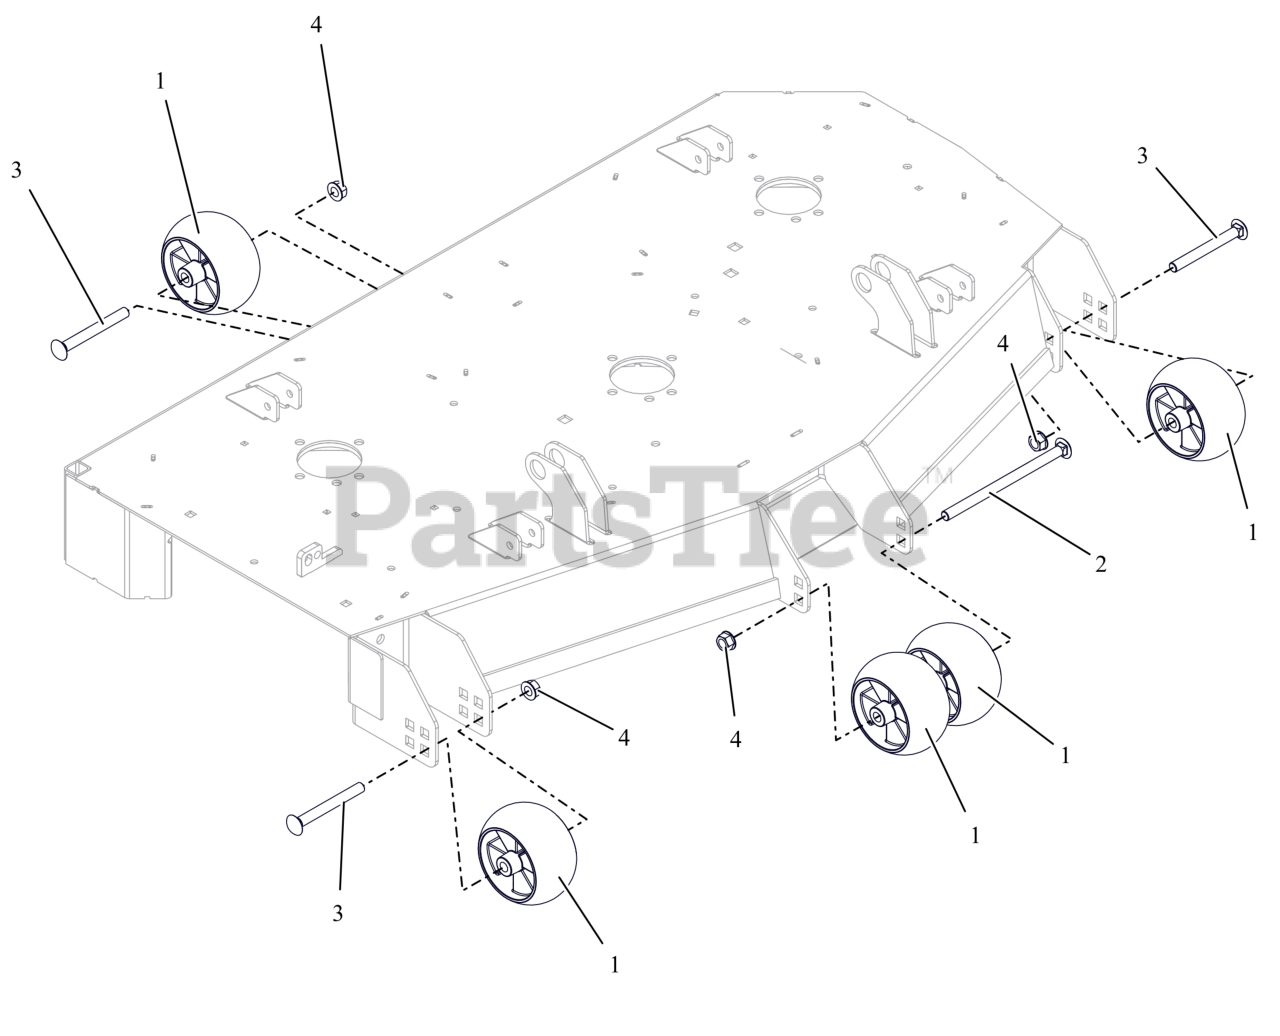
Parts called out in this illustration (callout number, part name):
1	WHEEL, ANTI SCALP - 5X3 CTR W/RIBS
2	BLT,RHSN .50-13X8.00 G5 ZCC NS
3	BLT,RHNS .50-13X4.50 G5 ZCC NS
4	NUT-LK-CTR-FLG .500-13 GG ZCC
